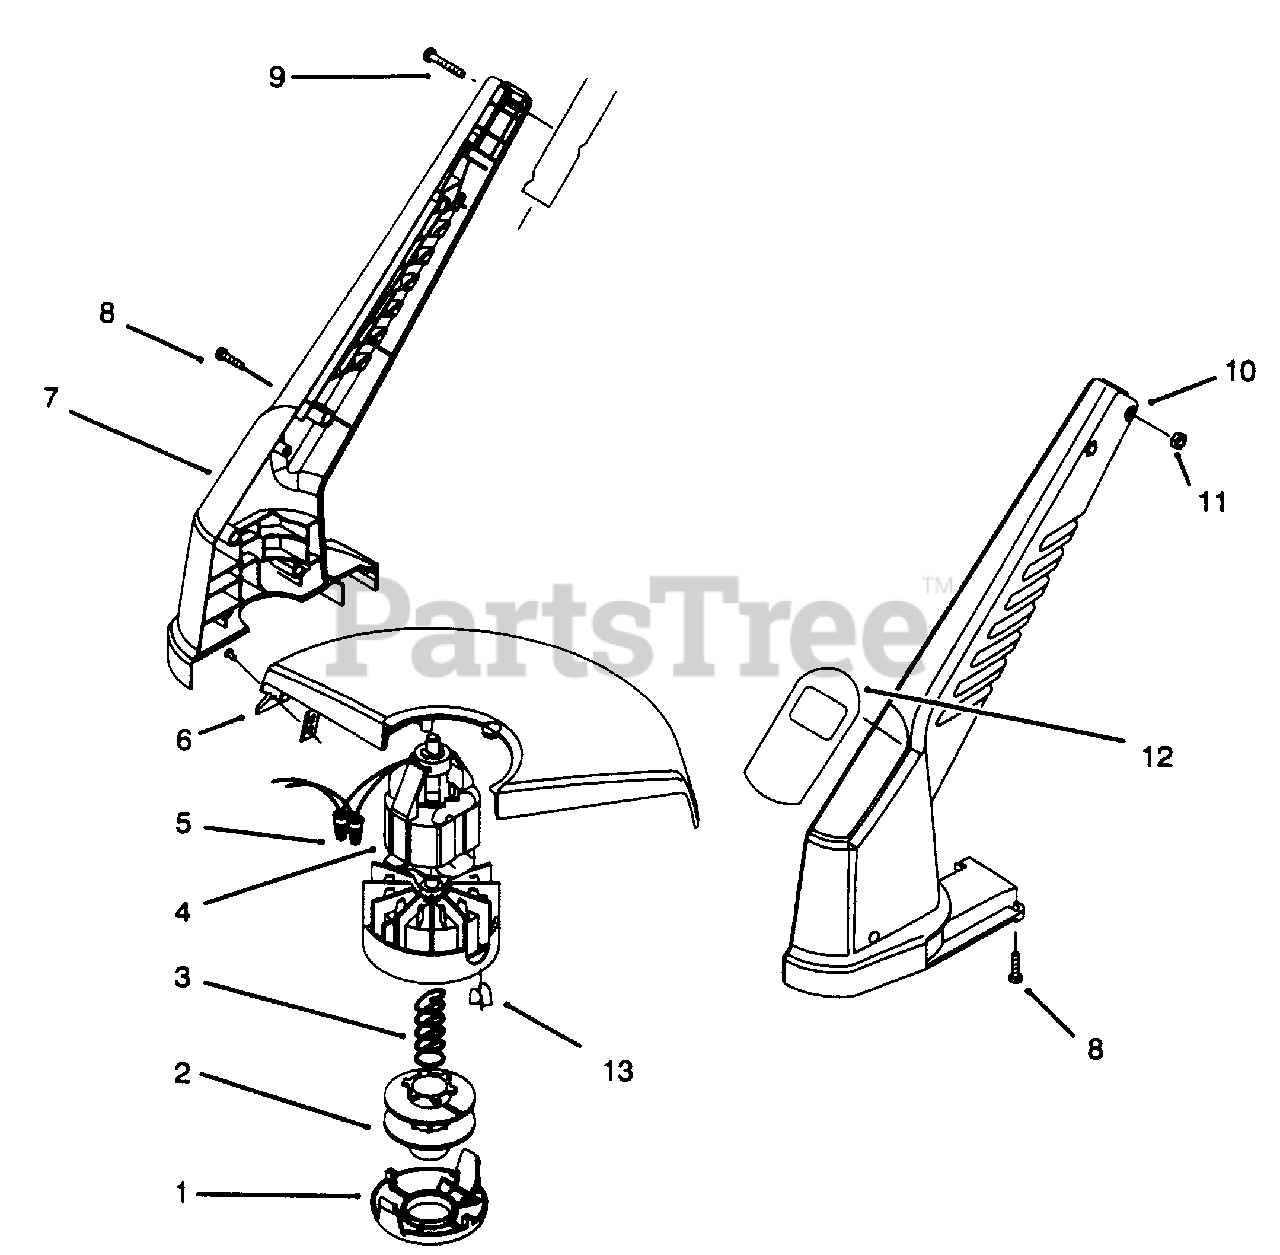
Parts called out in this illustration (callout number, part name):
4	Motor Assembly (Incl. Ref. #13)
5	Connector-Wire Nut
6	Shield-14"
7	Housing R.H.
8	Screw-Pan Hd. Tapping
9	Screw-Pan Hd.
10	Housing L.H.
12	Decal-14" Trimmer
